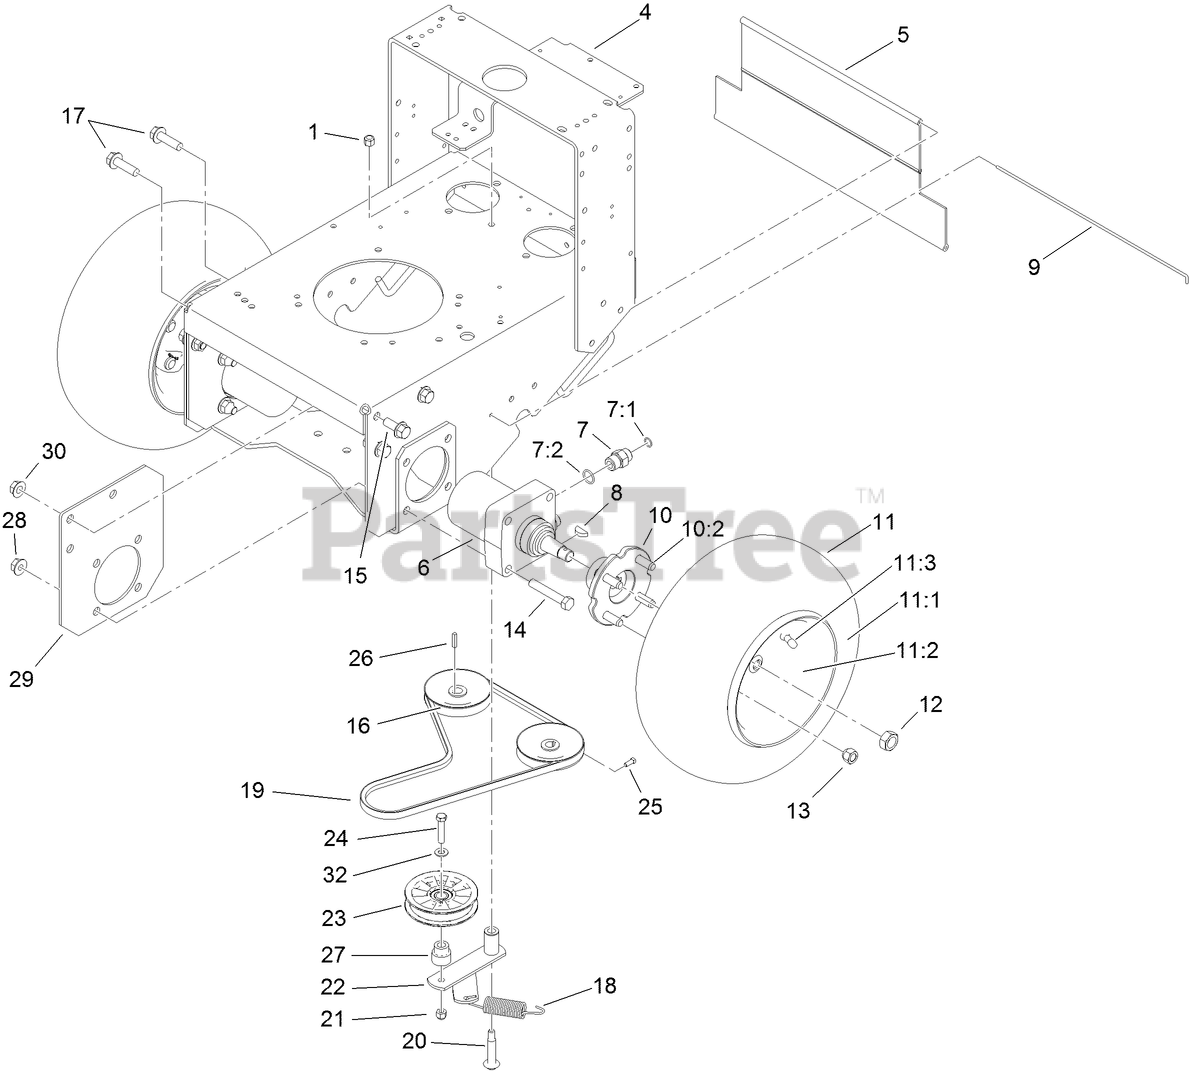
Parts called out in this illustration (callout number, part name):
1	NUT-LOCK
4	FRAME-HYDRO
5	SHIELD-TRAILING
6	HYD MOTOR ASM
7	FITTING-STRAIGHT
7:1	O-RING
7:2	O-RING
8	KEY-WOODRUFF
9	ROD-SHIELD
10	WHEEL HUB ASM
10:2	STUD-TYPE, DRIVE
11	WHEEL AND TIRE ASM
11:3	STEM-VALVE
12	NUT-MOTOR, WHEEL
13	NUT-LUG
14	SCREW-HH
15	SCREW-HHF
16	PULLEY-PUMP
17	SCREW-HHF
18	SPRING-TRACTION
19	BELT-V
20	BOLT-WHEEL
21	NUT-LOCK, NI
22	IDLER LEVER ASM
23	PULLEY-IDLER, FLAT
24	SCREW-HH
25	SCREW-SET
27	BUSHING-IDLER
28	NUT-HHF
29	PLATE-FRAME
30	NUT-HF
32	WASHER-FLAT
